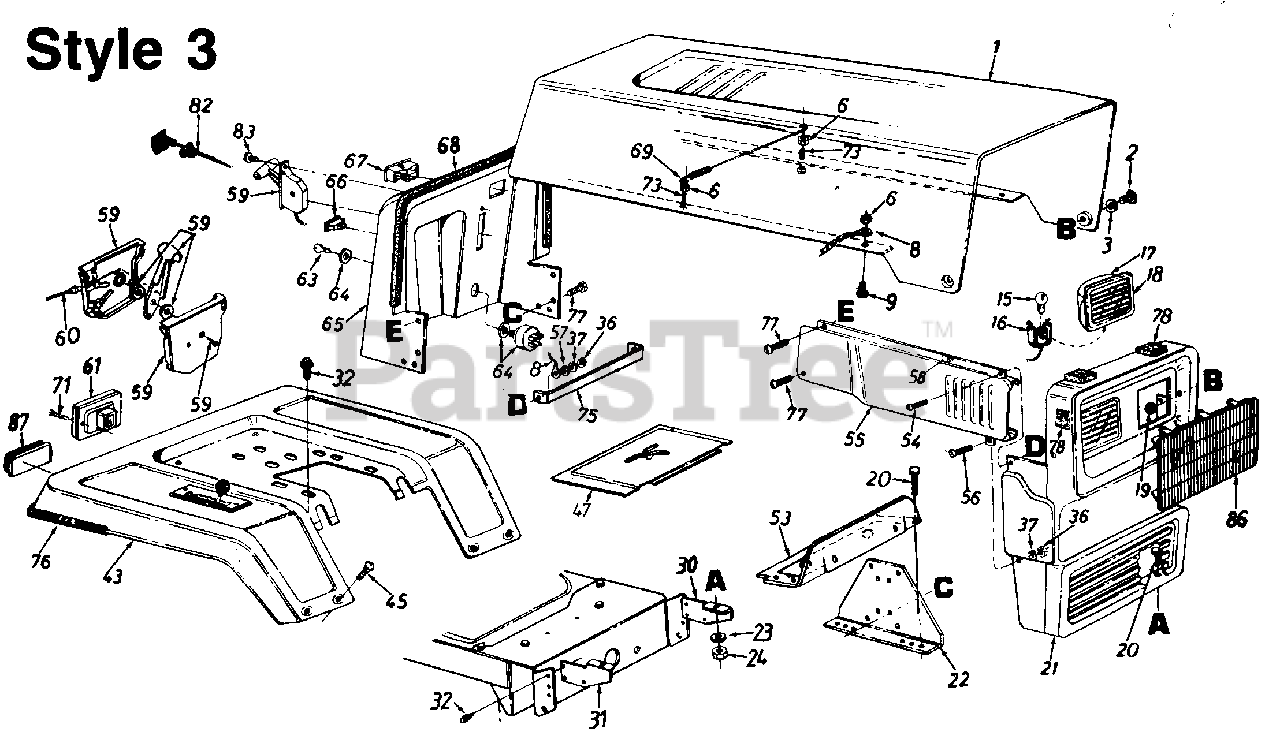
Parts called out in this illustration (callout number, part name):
3	Washer.39" I.D. x.62"
6	Hex Sems Nut #10-24 Thd.*
8	Hood Stop
9	Truss Hd. Scr. #10-24 x 1/2"*
15	Lamp
16	Twist Lock-Lamp Socket
17	Headlight Housing
18	Lens
19	L-Nut 1/4-28 Thd.
20	Hex Bolt 5/16-18 x .75" Lg.*
23	L-Wash. 5/16" I.D.*
24	Hex Nut 5/16-18 Thd.*
30	Grille Mount Brk't.-L.H.
36	Hex Nut 1/4-20 Thd.*
37	L-Wash. 1/4" I.D.*
43	Rear Fender
47	Transmission Panel
53	Support Brkt.
54	Truss Hd. Scr. 1/4-20 x .75"*
57	Fl-Wash. .281" I.D. x .73" O.D.
58	Mounting Clamp
59	Throttle Control Box Ass'y.
60	Throttle Control Wire
61	Taillight
63	Ignition Key
64	Ignition Switch
67	Ammeter
68	Trim Strip-31"
69	Hood Spring
71	Truss Hd. AB-Tap Scr. #6 x .62" Lg.
73	Hex Scr. #10-24 x 1.0" Lg.
75	Tie Strap-Grille/Side Panel
76	Trim Strip-81"
77	Hex Wash. Hd. Tap Scr. 1/4 x .75" Lg.
78	Foam Strip 3/8 x 1-1/8" x 11/2" Lg.
82	Choke Control 46" Lg.
83	Truss Mach. AB-Tap Scr. #10 x .5" Lg.
86	Headlight Bezel
87	Reflector
